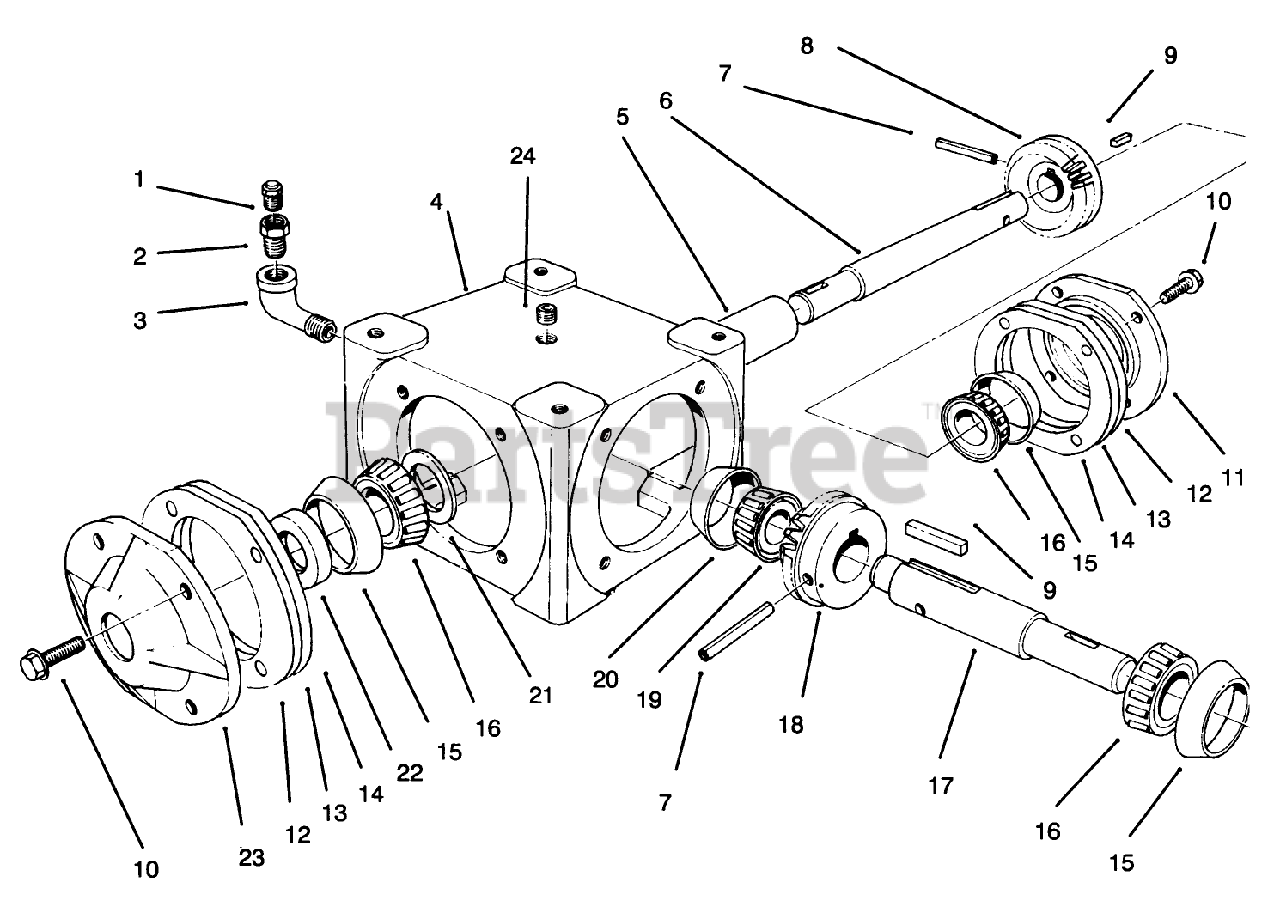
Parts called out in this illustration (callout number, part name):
1	Valve
2	BUSHING
3	Elbow-Street
4	HOUSING
5	SPACER
6	SHAFT
9	Key
10	SCREW-HH (OBS, C/R TO 3234-5)
12	GASKET
13	GASKET
14	GASKET
15	Cup
16	Cone
17	SHAFT
19	Cone
20	Bearing Cup
21	WASHER
22	Seal
24	PLUG (OBS, C/R TO 281-10)
